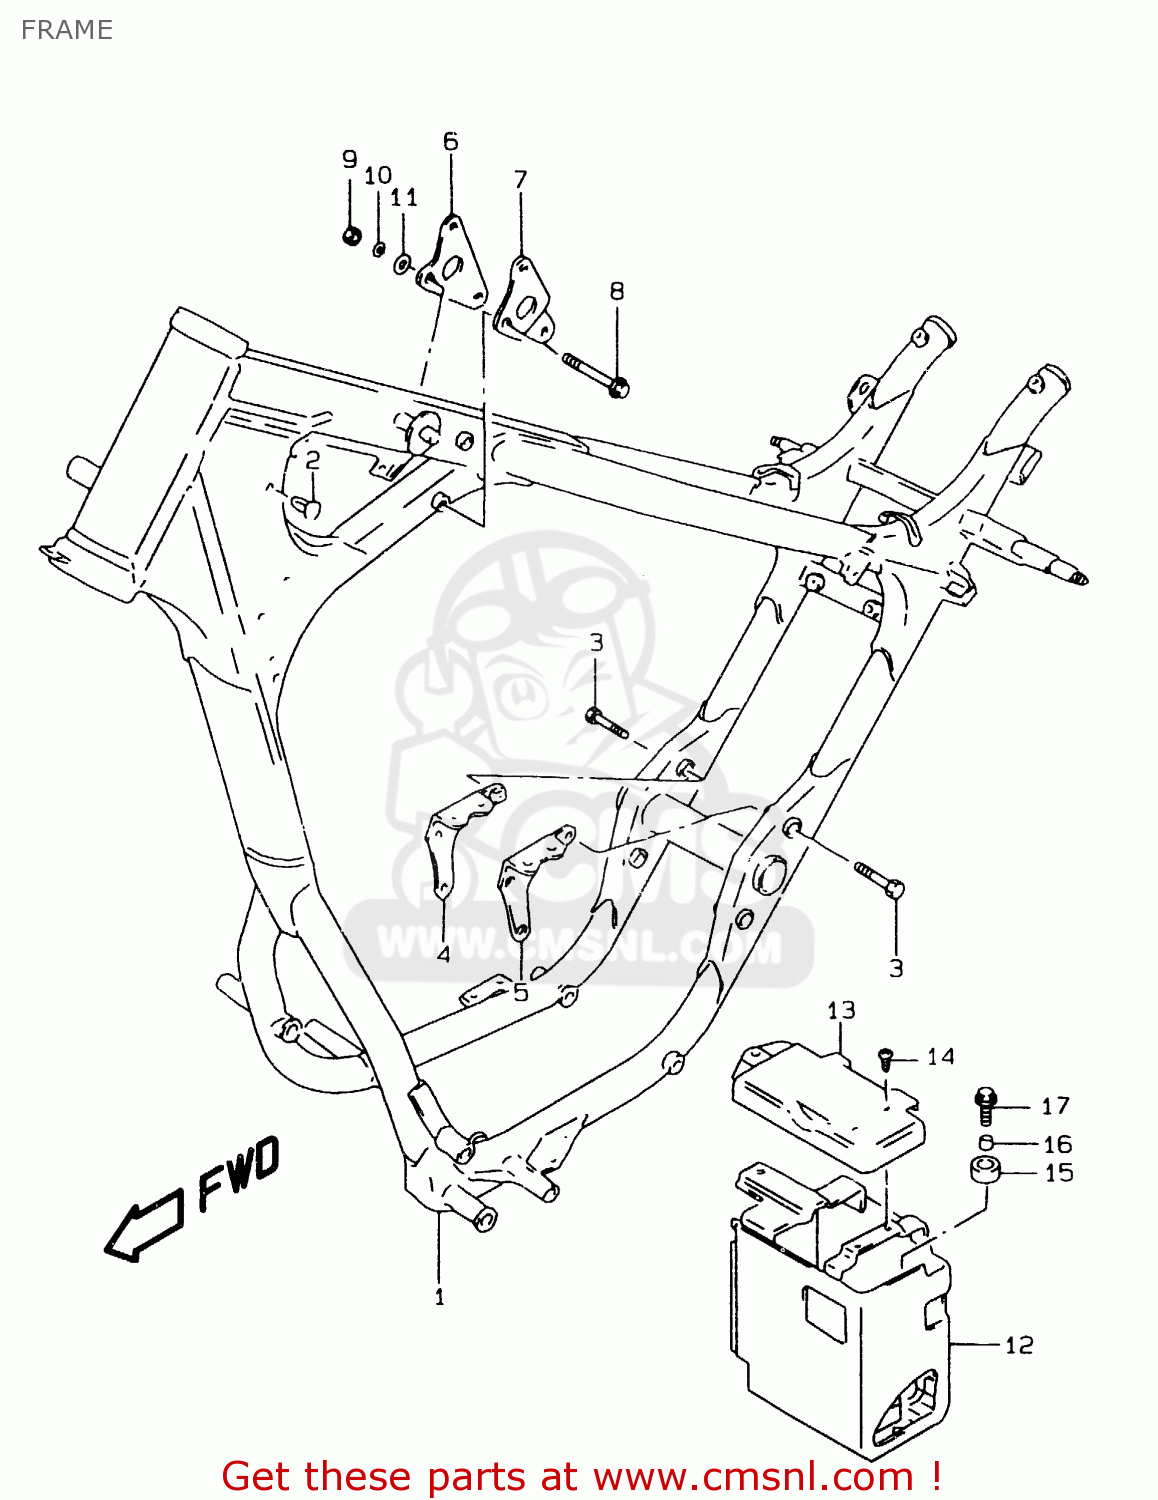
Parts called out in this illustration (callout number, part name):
1	FRAME(BLACK)
2	CLIP
3	BOLT(8X40)
4	PLATE,ENGINE MOUNT NO.4,R
5	PLATE,ENGINE MOUNT NO.4,L
6	PLATE,ENGINE MOUNT NO.5,R
7	PLATE,ENGINE MOUNT NO.5,L
8	BOLT(8X72)
9	NUT
10	LOCK WASHER
11	WASHER
12	HOLDER,BATTERY
13	COVER,BATTERY
14	SCREW
15	CUSHION
16	SPACER
17	BOLT
